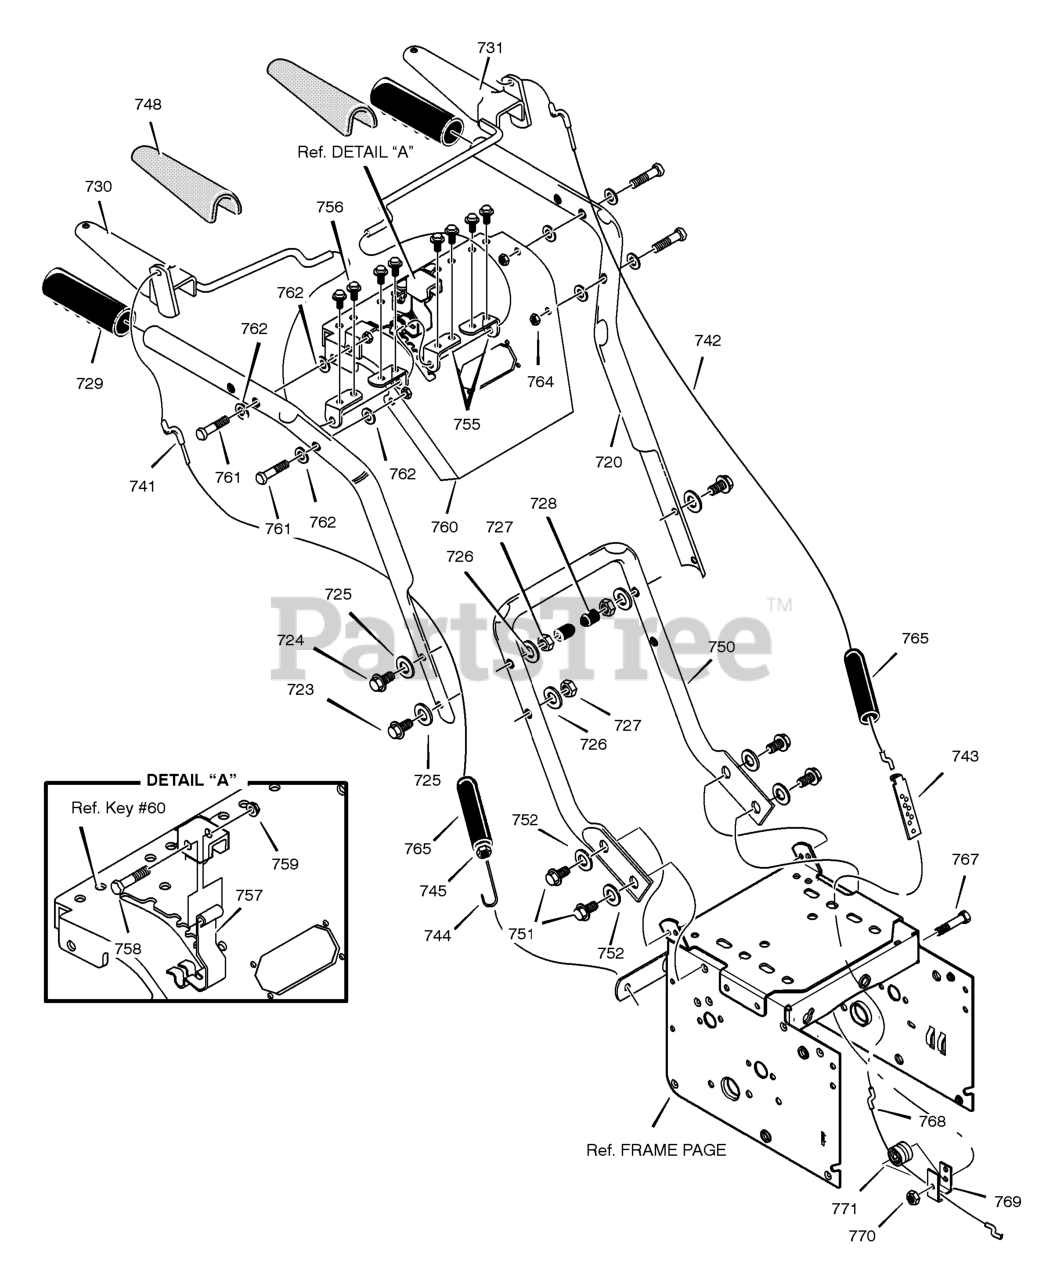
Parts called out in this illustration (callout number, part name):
720	HANDLE, UPPER LH
721	HANDLE, UPPER RH
723	SCREW
724	SCREW
725	WASHER, FLAT
726	WASHER, SPTLK
727	NUT, REGHEX
728	STOP, PLASTIC
729	GRIP-HANDLE
730	LEVER, ASSY CLUTCH DRIVE RH
731	LEVER, ASSY CLUTCH DRIVE LH
741	CABLE, AUGER CLUTCH
742	CABLE, AUGER DRIVE
743	BRACKET, CABLE ADJUSTER
744	SPRING, AUGER CLUTCH
745	NUT, 1/4-20
748	GRIP, CLUTCH HANDLE
750	HANDLE, LOWER
751	SCREW, TAP 5/16-18 X .75
752	WASHER, SPTLK
754	SCREW
755	BRKT, ROD
756	SCREW
757	SPRING, CAM LOCK
758	BOLT, HEX
759	NUT
761	SCREW
762	WASHER, FLAT
764	NUT, HEXFLNG
765	BOOT, CLUTCH SPRING
767	BOLT, HEX 1/4-20 X 1.75 YZ
768	CABLE, LOWER DRIVE 12"
769	BRACKET, CABLE SPOOL YZ
771	SPOOL-CABLE, AUGRT CLUTCH
772	SPRING, AUGER CLUTCH
